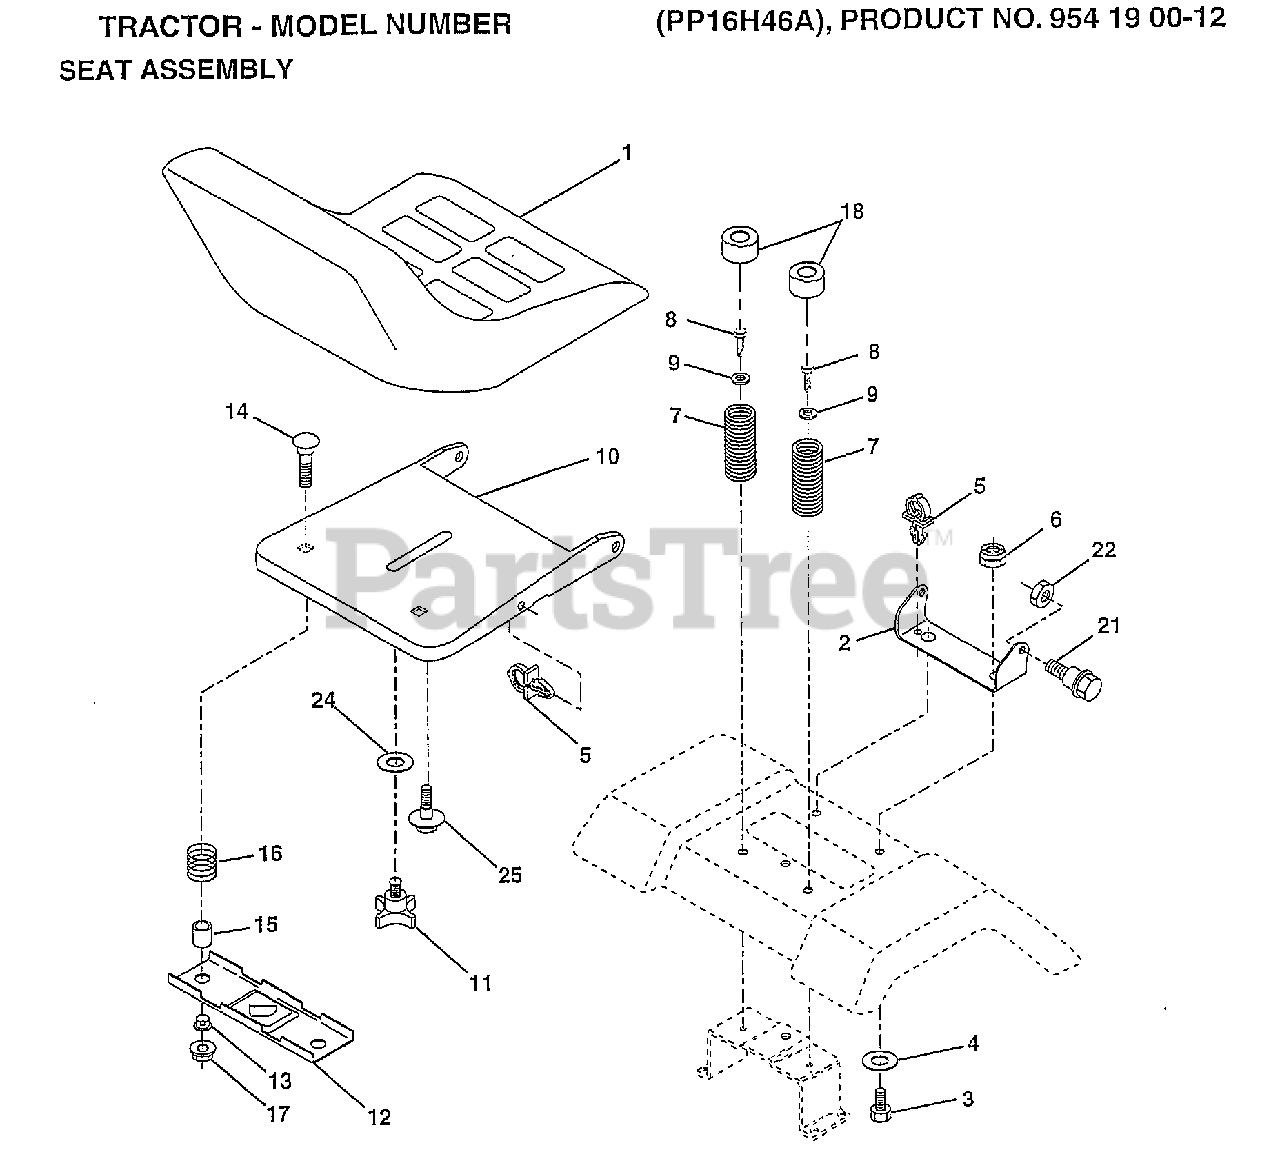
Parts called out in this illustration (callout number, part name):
1	SEAT.2500/1516.BK
2	BRACKET PVT SEAT
3	BOLT
4	WASHER PM
5	CLIP.PUSH-IN.HING
6	NUT
7	SPRING, COMPRESSION, SEAT
8	SCREW GTV
9	WASHER
10	PAN-SEAT
11	"KNOB 1/2"" YT"
12	BRKT SWITCH
13	BUSHING
15	SPACER SPLIT
16	SPRING COMPRESSED
18	CAP SPRING
21	"BOLT,SHOULDER"
22	NUT
24	WASHER
25	"BOLT,SHOULDER"
